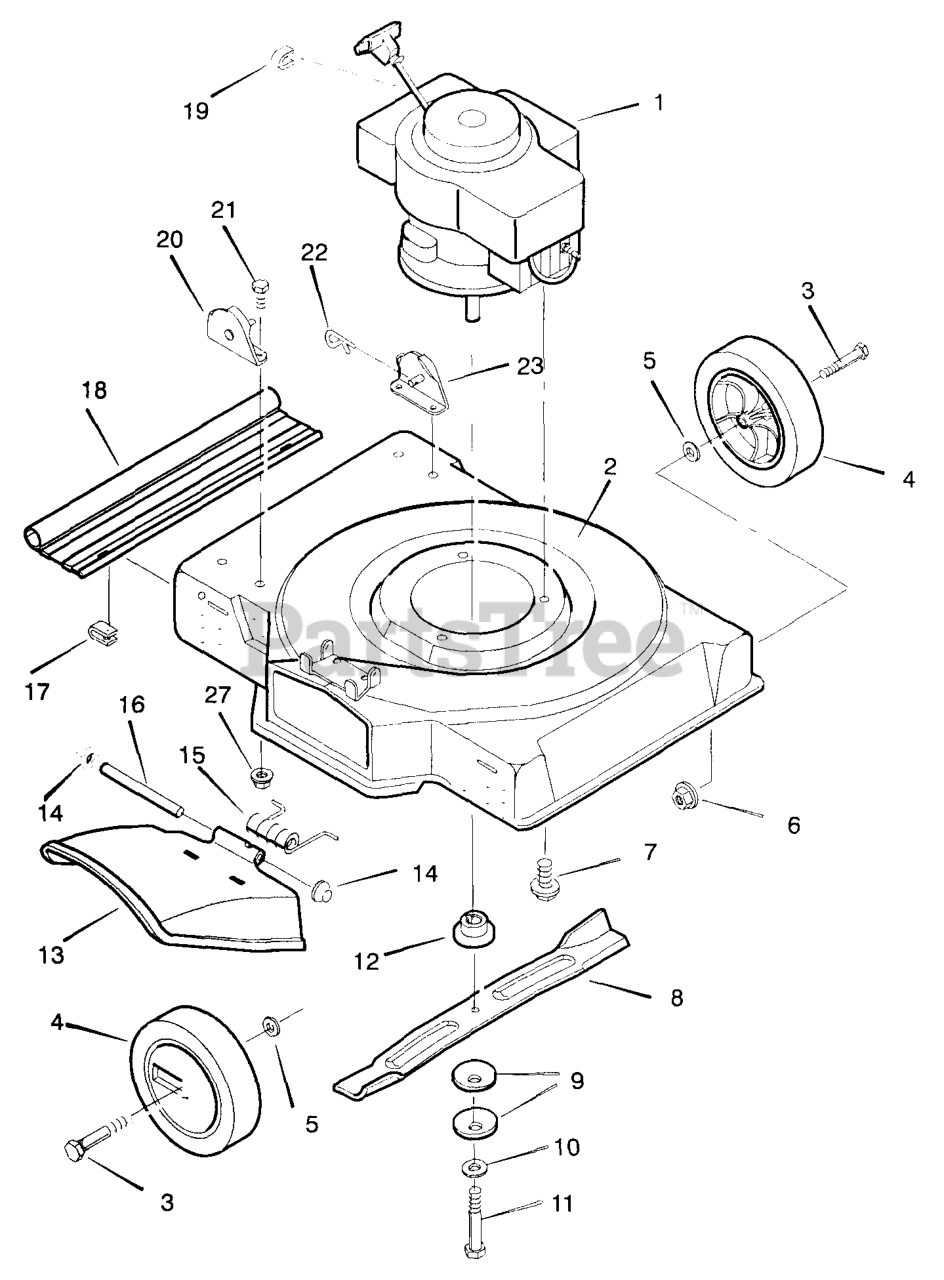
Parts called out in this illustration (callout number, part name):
1	Engine *
2	Housing, For Folding Handle
3	Bolt, Axle
4	Wheel and Tire *
6	Locknut, Flange
7	Bolt, Engine
9	Washer, Belleville
11	Bolt, Hex
12	Adapter, Blade
13	Deflector, Chute
14	Push-On Cap
16	Pin, Pivot
17	Retainer
18	Deflector, Rear
19	Stop, Rope
20	Bracket, Right Handle
22	Pin, Hair
23	Bracket, Left Handle
27	Nut
